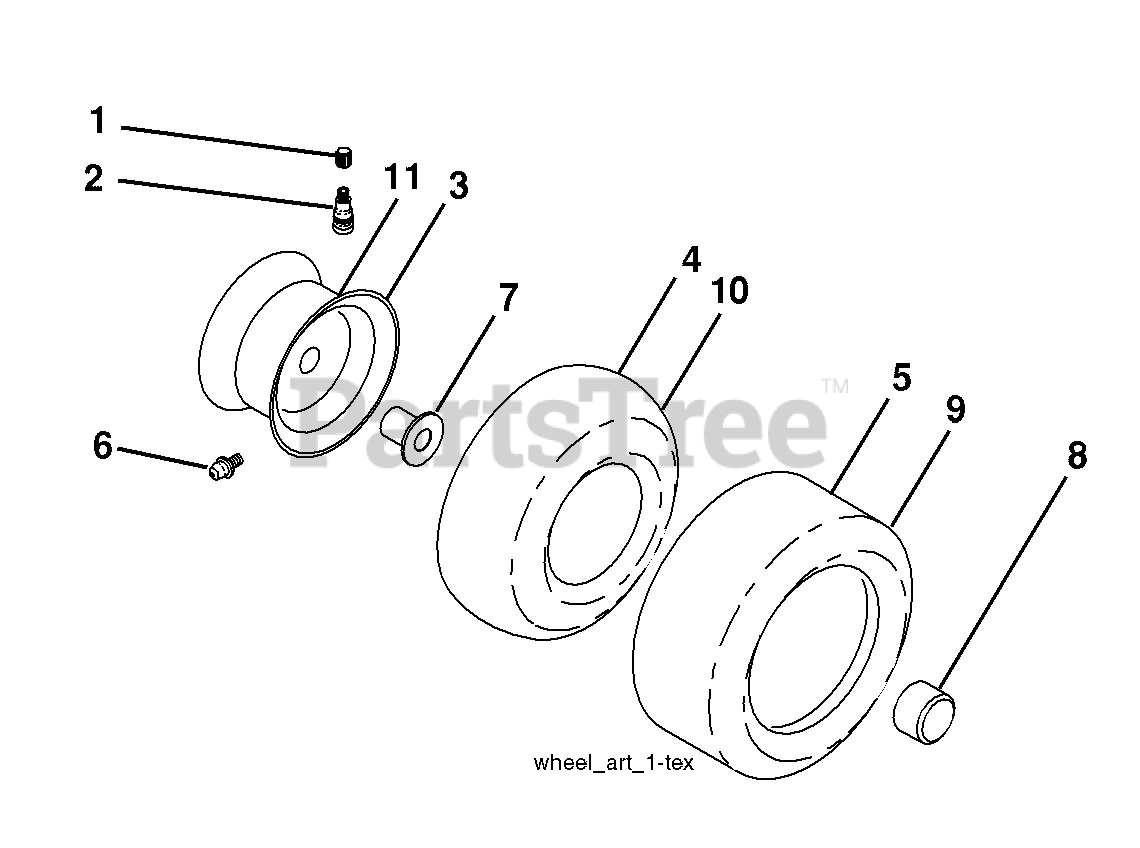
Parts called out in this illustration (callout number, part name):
1	Cap Valve Tire
2	Stem Valve
3	Rim Asm 6" front
4	Tube Front
5	Tire Front 15 x 6.0-6 Service
6	Fitting Grease
7	Bearing Flange
8	Cap Axle Blk 1 50 x 1 00
9	Tire Rear 18 x 9.5-8 "Turf Saver"
9	Tire Rear 18 x 9.5-8 "Turf Saver LT"
10	Tube Rear
11	Rim Asm 8" rear
11	Sealant, Tire
